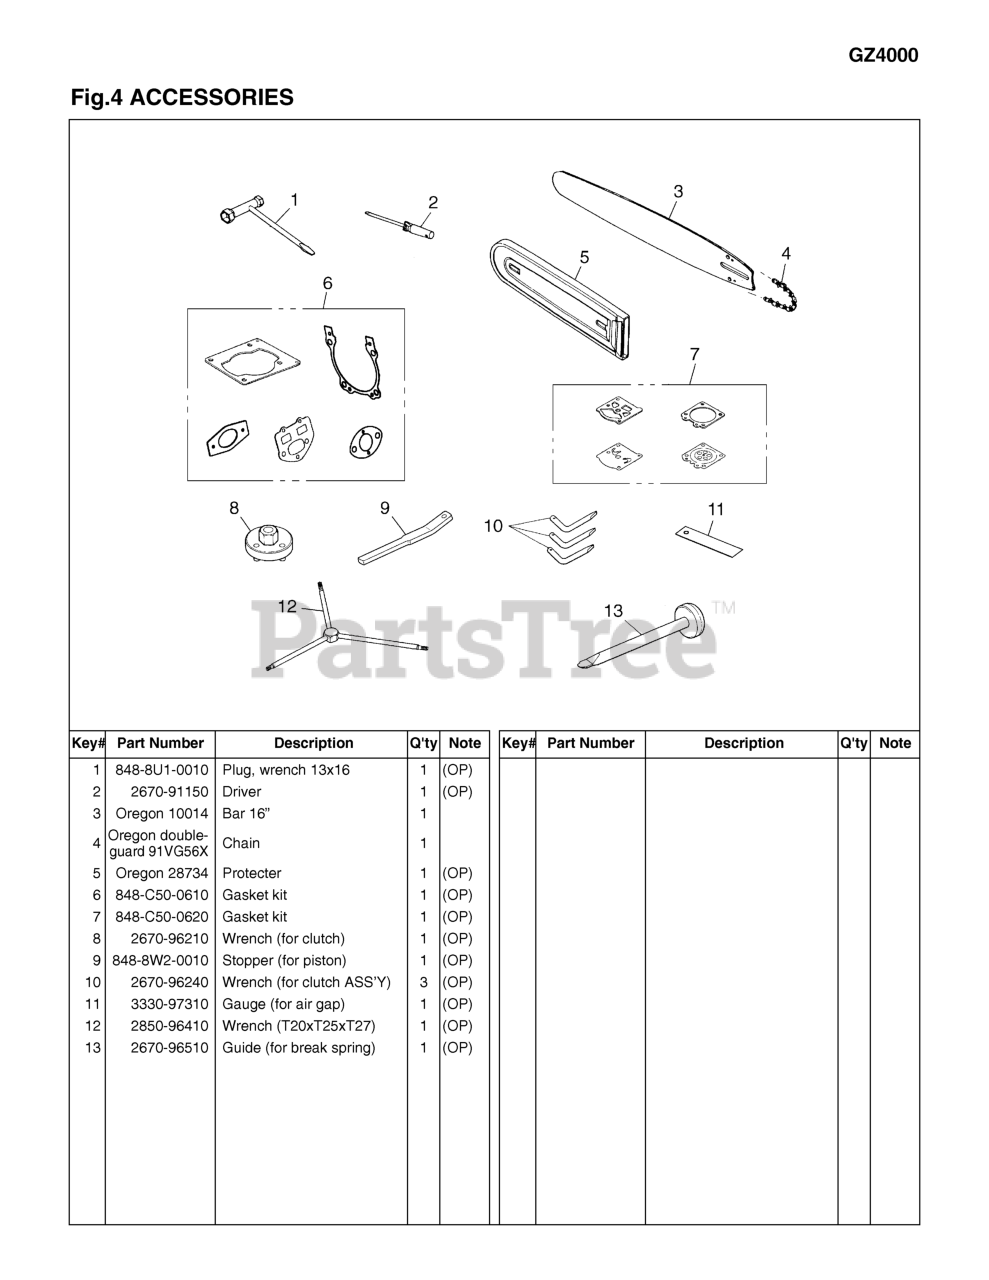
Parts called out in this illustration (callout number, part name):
1	WRENCH
2	SCREWDRIVER
3	BAR 16
5	PROTECTOR (OREGON 28734)
6	GASKET KIT (ENG)
7	GND-27- G-KIT
8	WRENCH (TOOL)
9	STOPPER
10	WRENCH (TOOL)
11	GAUGE (TOOL)
12	WRENCH (RPLS. 2670-96410)
13	GUIDE (TOOL)
